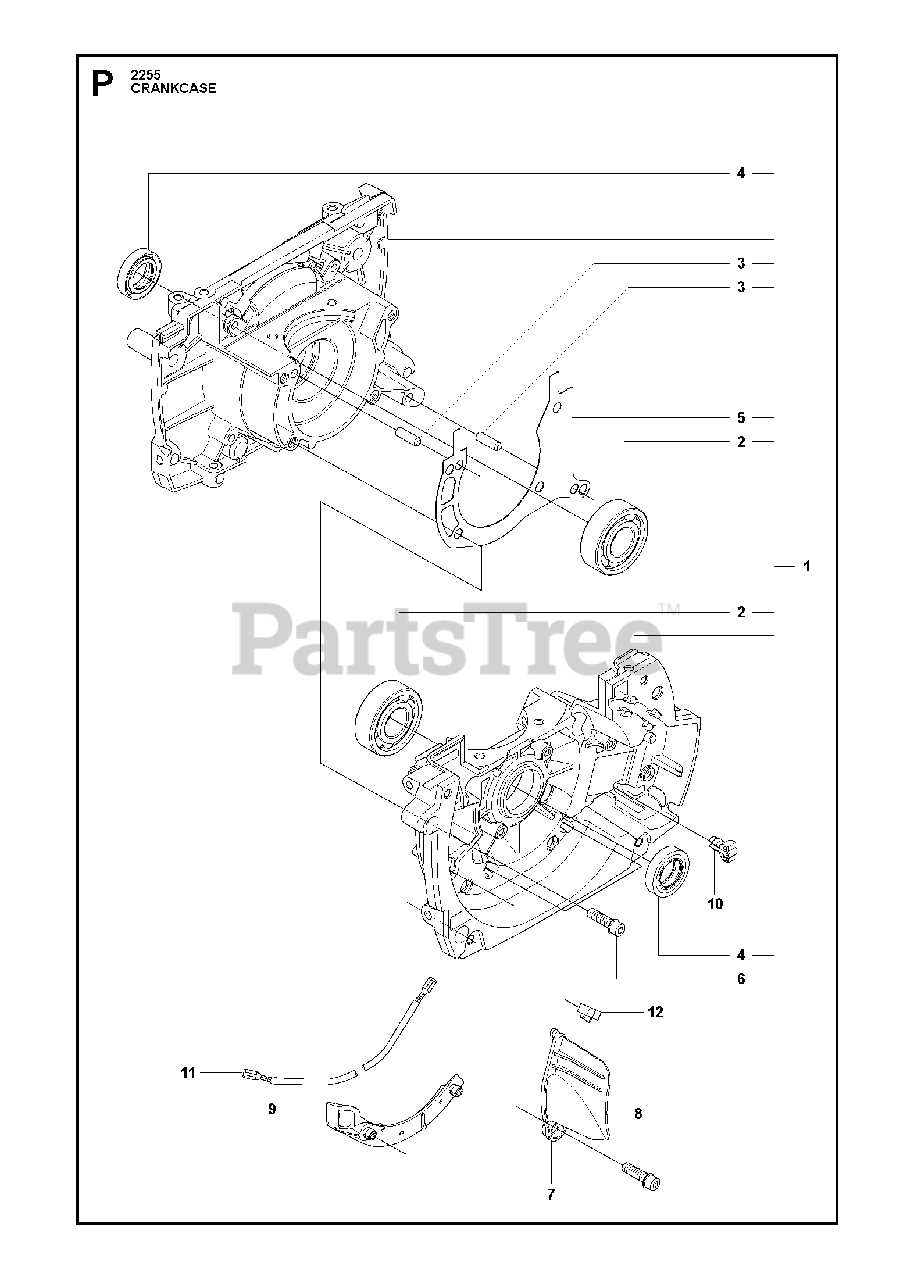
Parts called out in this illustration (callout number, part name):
1	CRANKCASE
2	BALL BEARING
3	PIN 5X14
4	SEALING RING
5	CRANKCASE GASKET
6	SCREW MC6S 5X25
9	CABLE HOLDER
11	SHORT CIRCUIT CABLE
